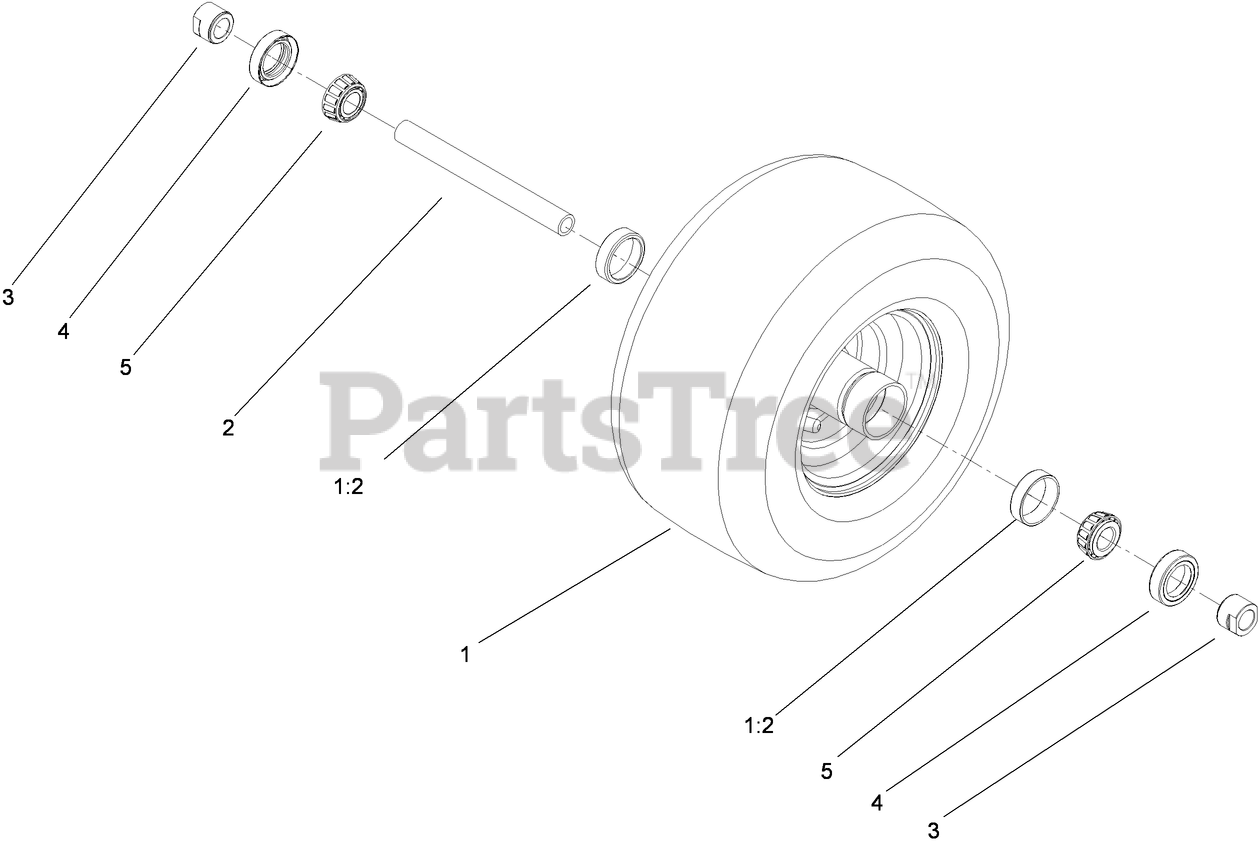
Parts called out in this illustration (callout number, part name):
1	WHEEL AND TIRE ASM
1:2	BEARING-CUP
2	AXLE-CASTER
3	SPACER-NUT
4	SEAL-CASTER
5	BEARING-CONE, TAPER
